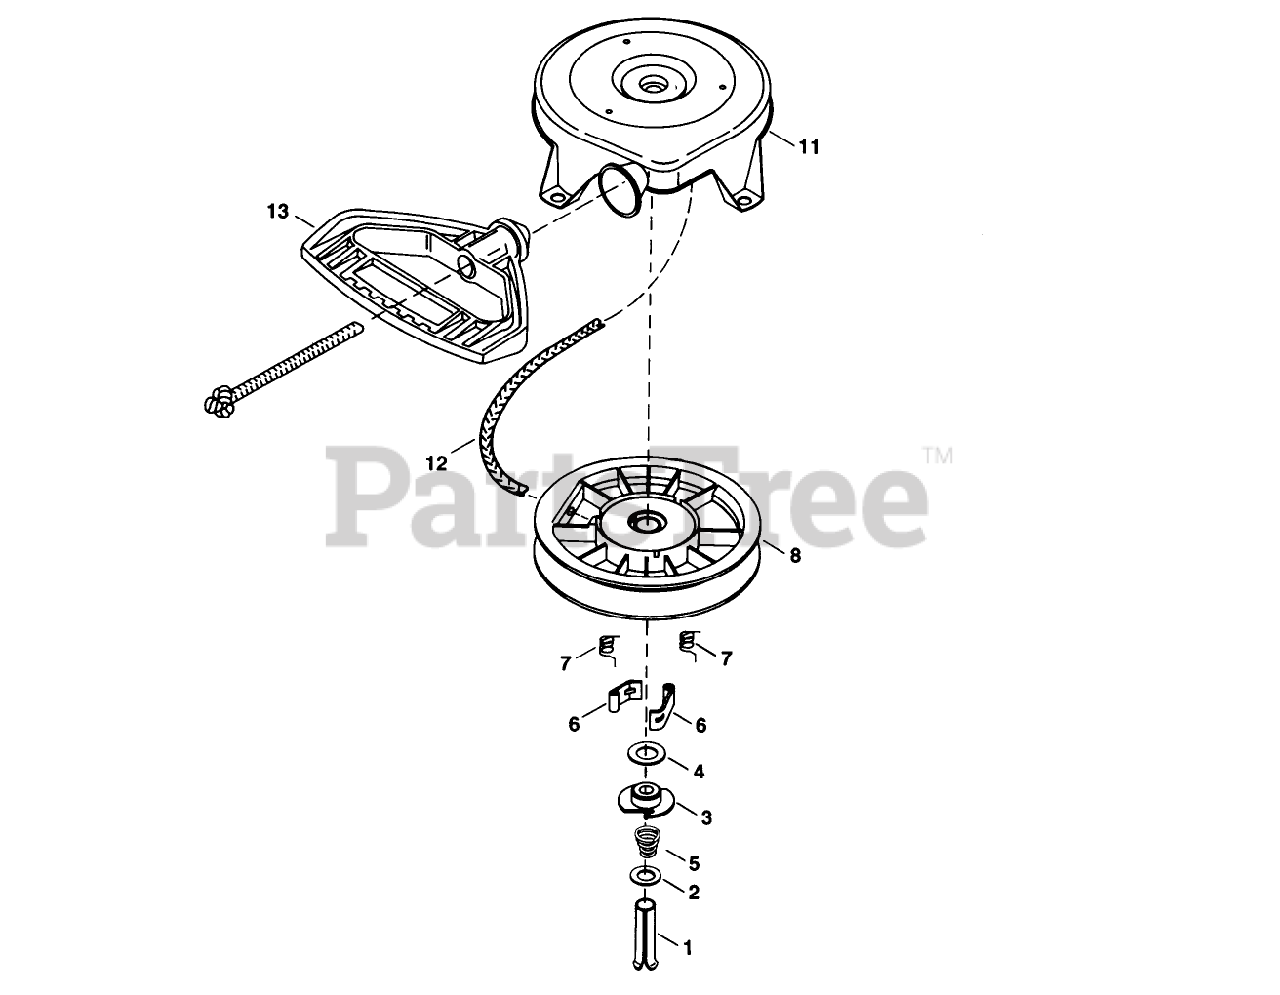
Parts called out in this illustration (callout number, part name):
1	Pin, Spring (Incl. Ref. #7)
2	Washer
3	Retainer
4	Washer
5	Spring-Brake
6	Dog-Starter
7	Spring-Dog
8	Pulley and Rewind Spring ASM
11	Housing Assy.-Starter
12	Rope-Starter
13	Handle-Starter, Mitten Grip
